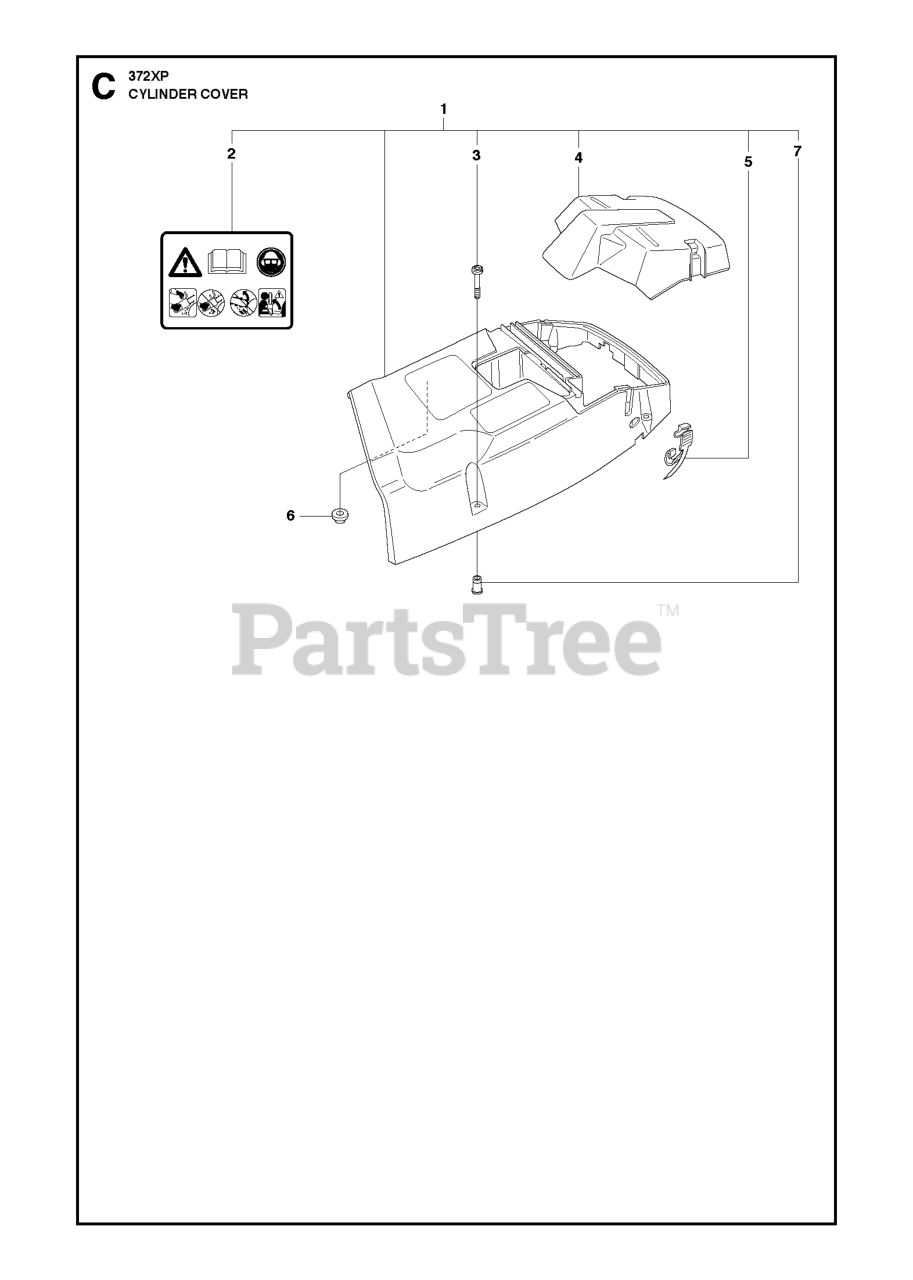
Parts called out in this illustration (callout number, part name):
1	TOP COVER
3	SCREW CITXPANMO
4	COVER
7	SLEEVE CYLINDER
